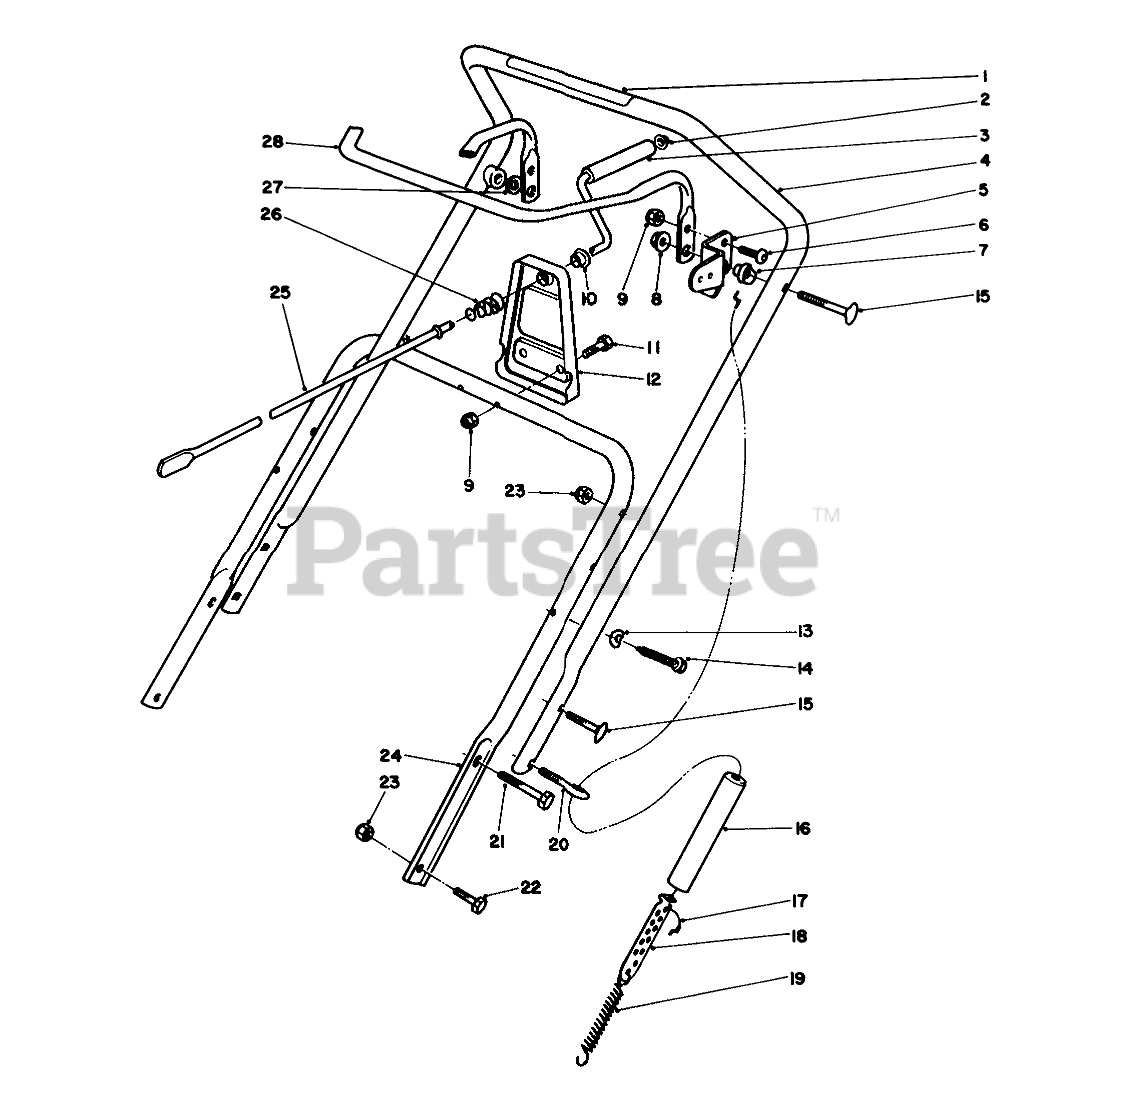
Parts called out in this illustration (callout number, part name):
1	DECAL - ROTOR DRIVE
2	RETAINER-PUSH ON
3	Grip-Rod
4	Upper Handle Assembly (Incl. Ref. #1:66-6870)
5	Arm-Clutch Cable
6	SCREW-HSBH
7	SPACER-BAR, CONTROL
8	NUT-LOCK, CAP
9	NUT-LOCK, NI
10	Bushing
11	SCREW-HH
12	Support-Crank
13	WASHER
14	SCREW
15	SCREW
16	COVER-SPRING
17	CABLE-CLUTCH
18	ADJUSTER-CABLE
19	SPRING-EXTENSION
20	BOLT-EYE
21	SCREW-HH
22	SCREW-HH
23	NUT-LOCK, NI
24	LOWER HANDLE
25	ROD-CRANK, CHUTE
26	SPRING-COMPRESSION
27	WASHER
28	Bar-Control
